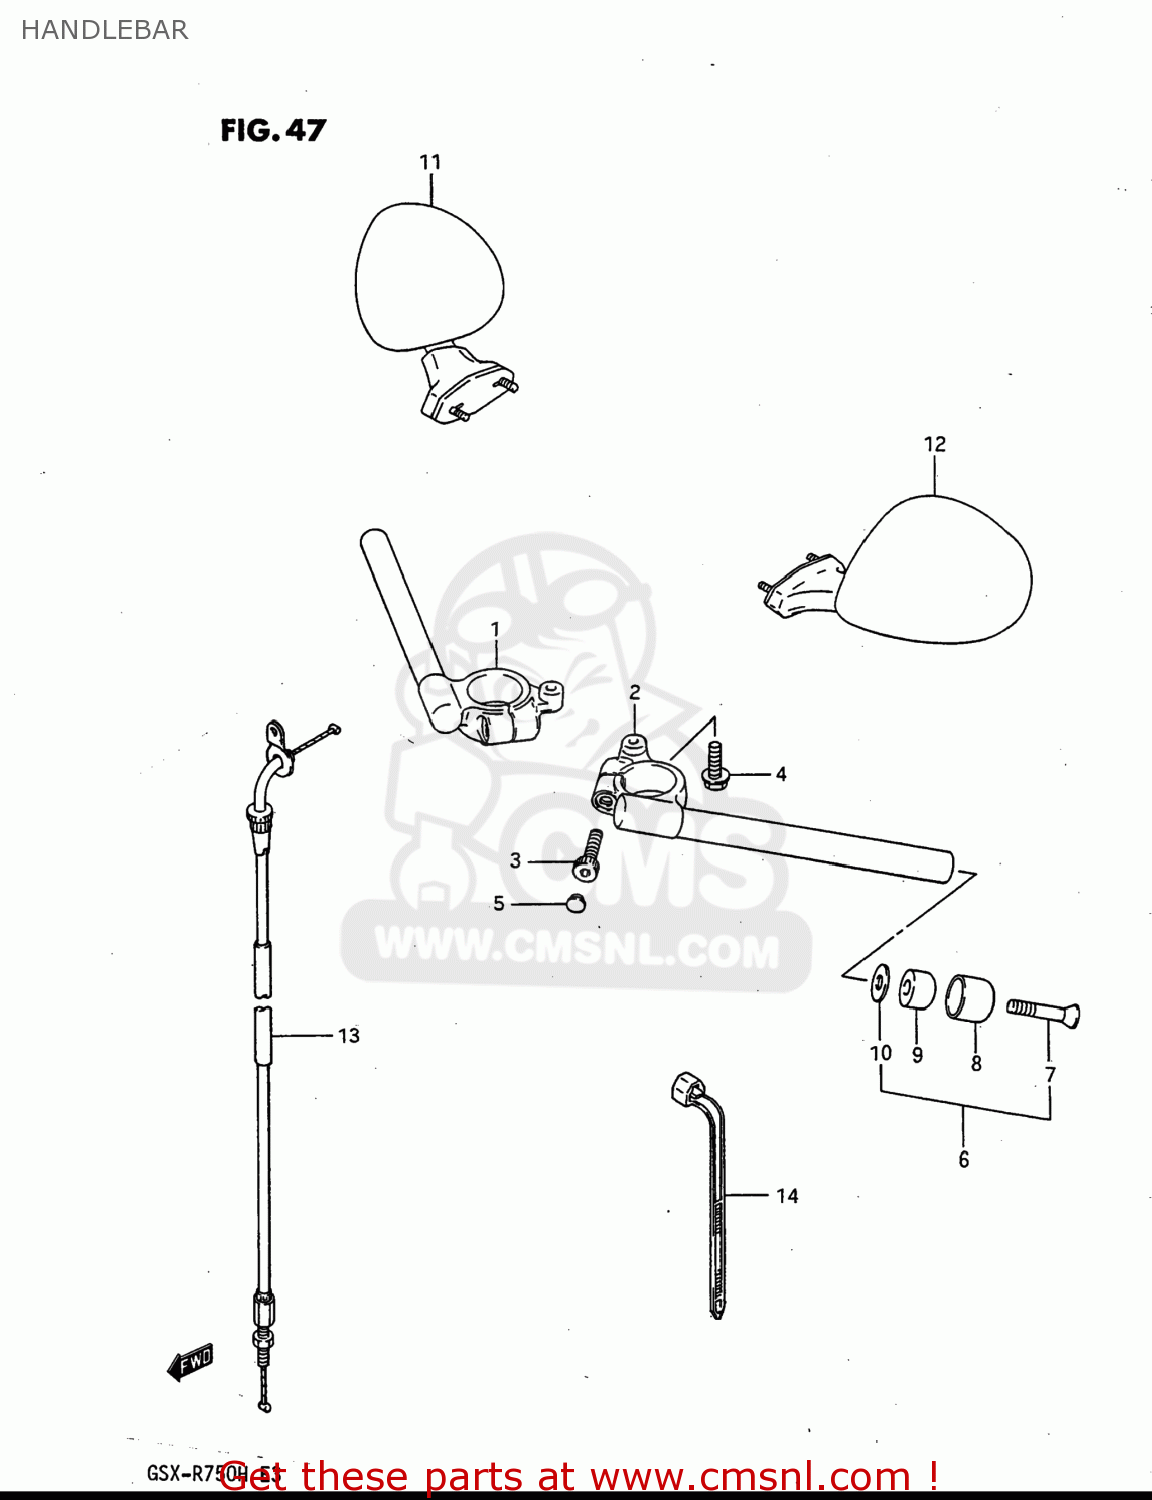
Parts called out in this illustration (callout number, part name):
1	HANDLEBAR,RIGHT
2	HANDLEBAR,LEFT
3	BOLT 8X35
4	BOLT
5	CAP(OD:10)
6	BALANCER SET,HANDLEBAR
7	SCREW
8	CAP,BALANCER
9	BALANCER,HANDLE
10	SPACER,BALANCER
11	MIRROR ASSEMBLY,RIGHT
12	MIRROR ASSEMBLY,LEFT
13	CABLE ASSY,THROTTLE
14	CLAMP(L:165)
